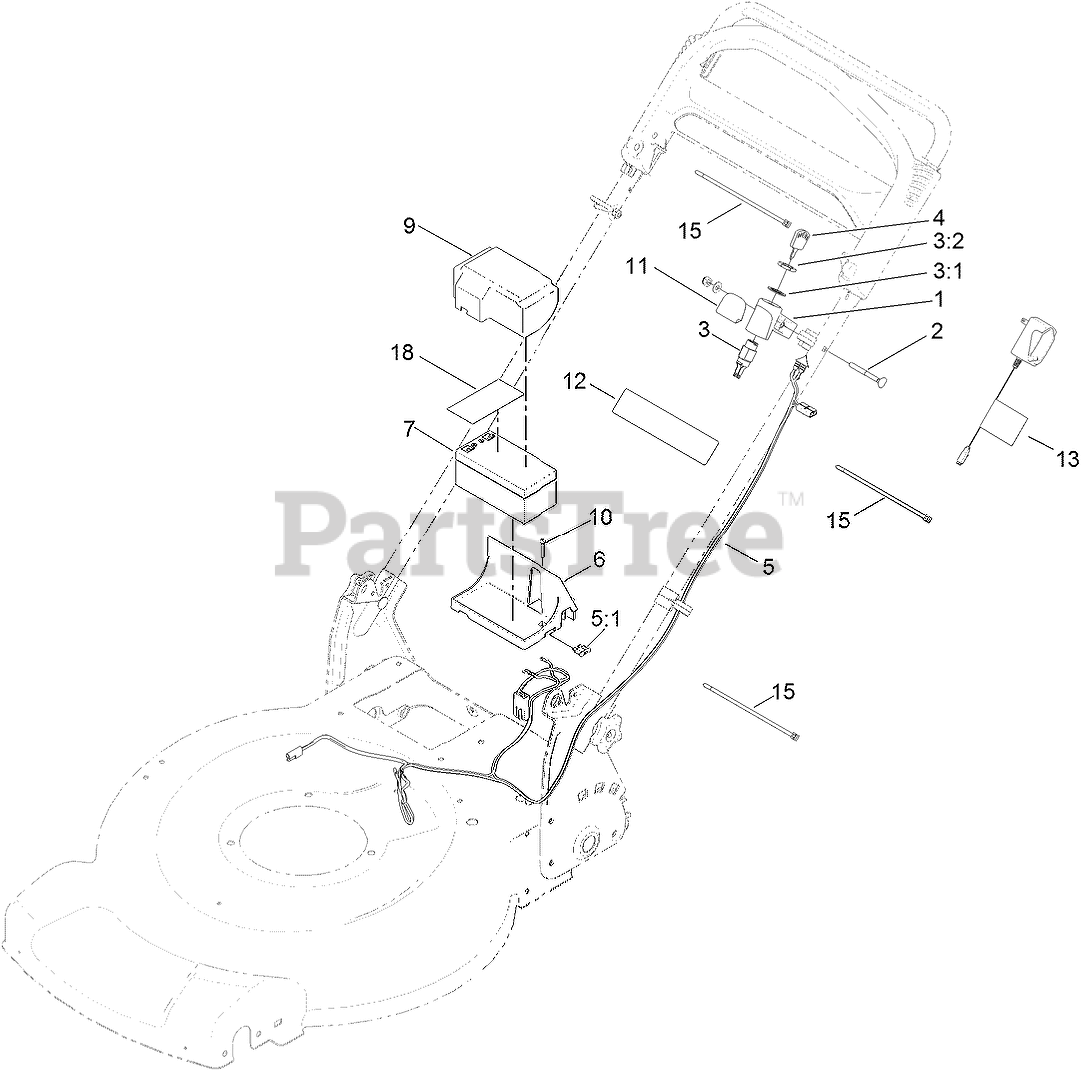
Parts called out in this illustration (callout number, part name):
1	MOUNT-SWITCH
2	SCREW-HANDLE
3	STARTER SWITCH ASM
3:1	WASHER-TOOTH, INTERNAL
3:2	NUT-HH
5	HARNESS-WIRE
5:1	FUSE-40 AMP
6	TRAY-BATTERY
7	BATTERY-WET
9	COVER-BATTERY
10	SCREW-PPH, PLASTITE
11	DECAL-ELECTRIC START
12	DECAL-WARNING
13	CHARGER-BATTERY
15	TIE-CABLE
18	DECAL-TERMINAL, BATTERY
